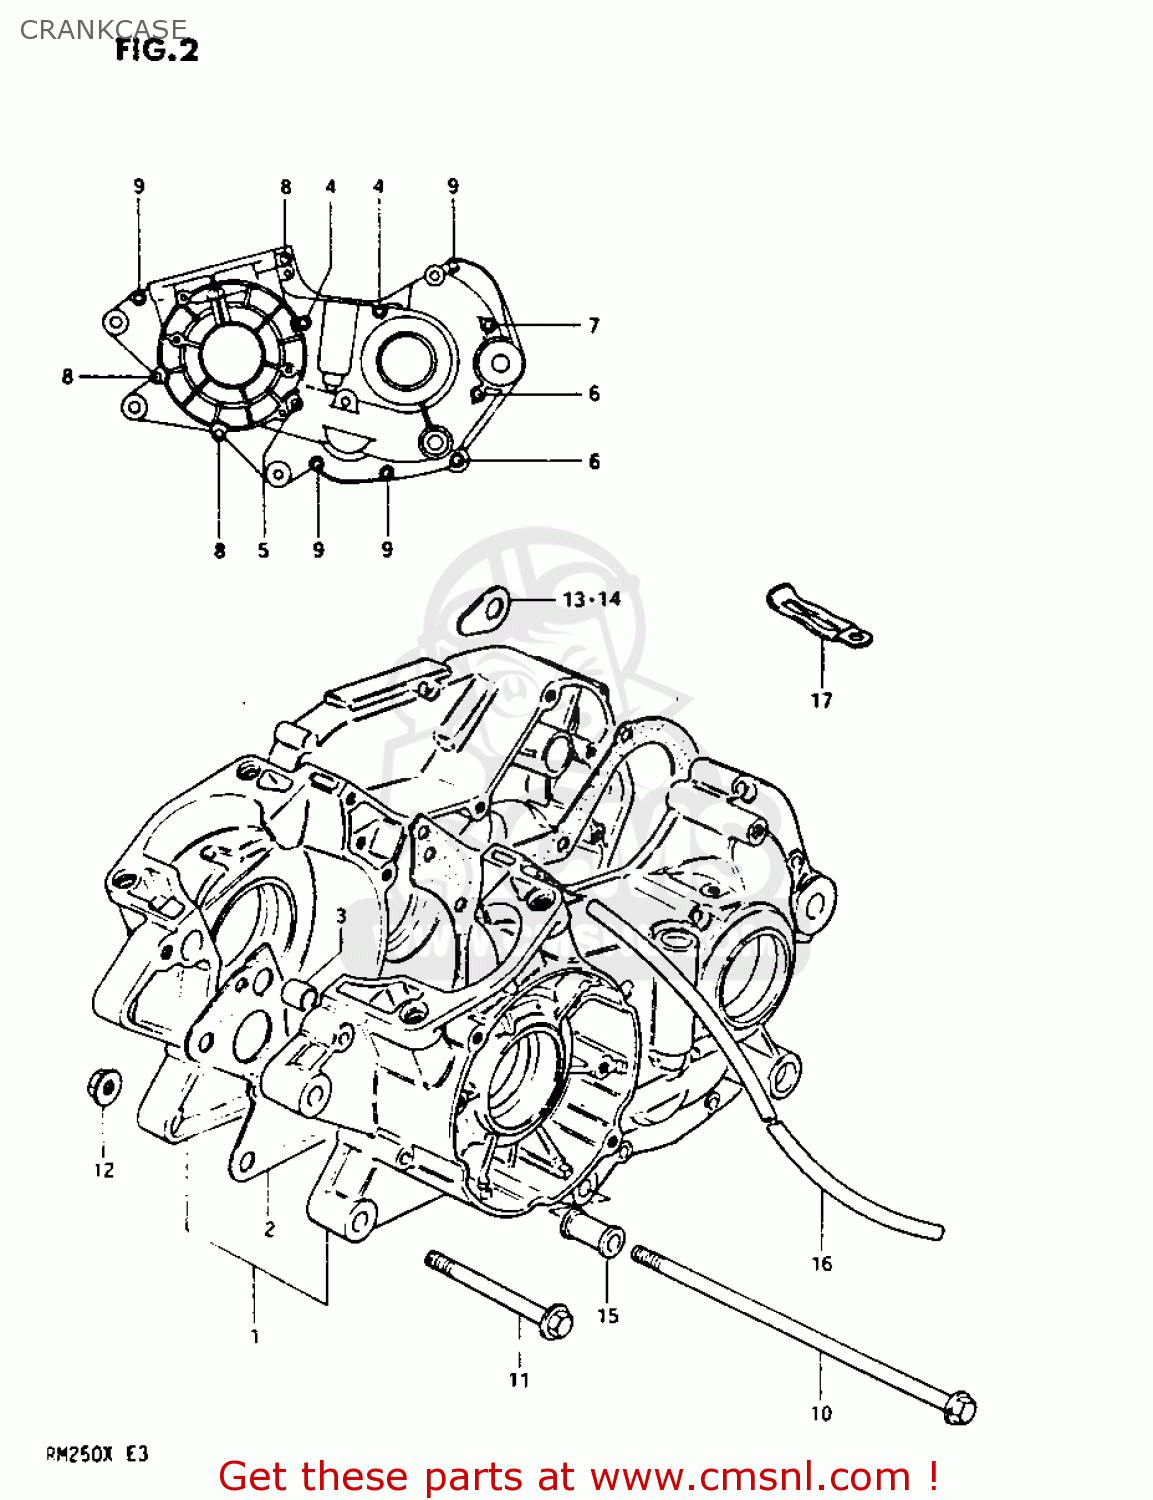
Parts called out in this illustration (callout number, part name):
1	CRANKCASE ASSEMBLY (ASB)
2	GASKET,CRANKCASE (MCA)
3	PIN
4	SCREW 6X70
5	SCREW 6X60
6	SCREW
7	SCREW
8	SCREW
9	SCREW
10	BOLT
11	BOLT(8X75)
12	NUT
13	WASHER
14	WASHER
15	SPACER,ENGINE MOUNT
16	HOSE
17	CLAMP
